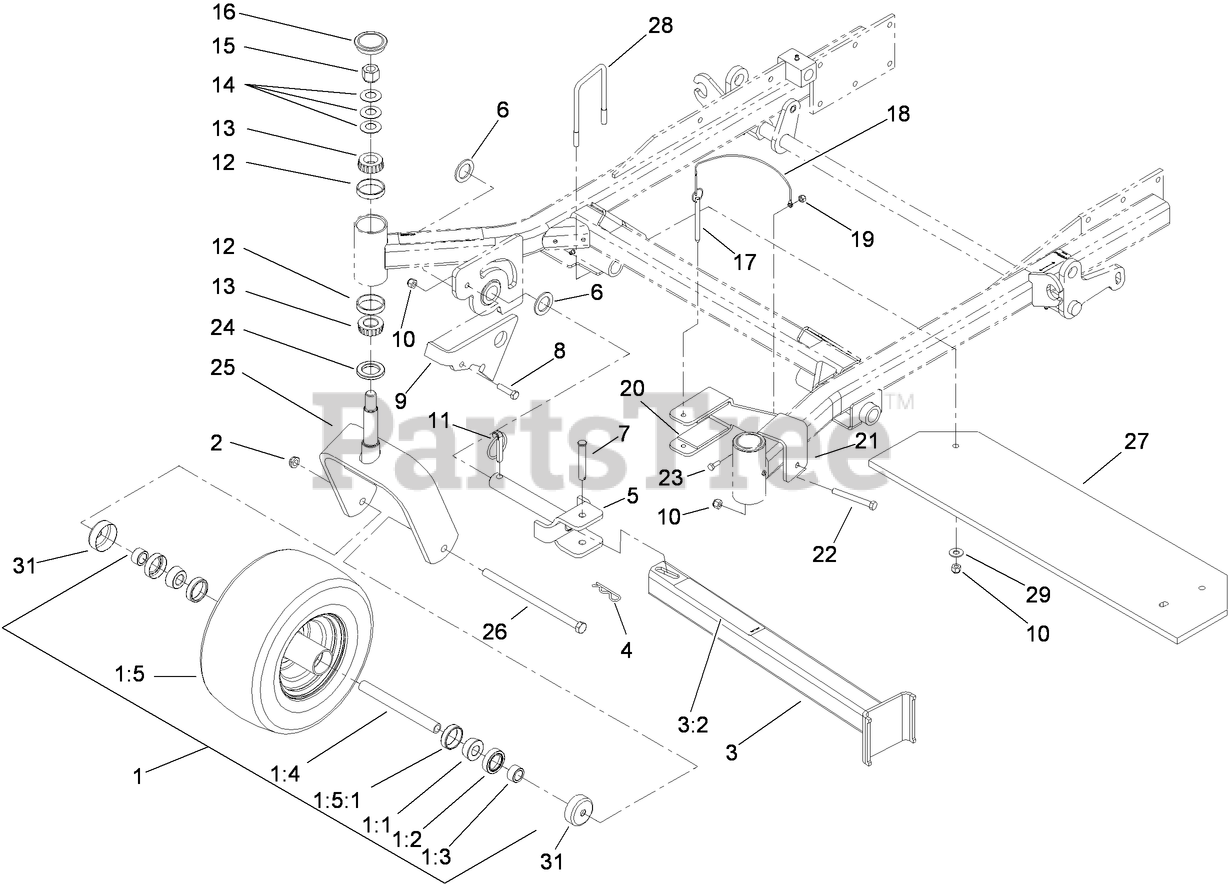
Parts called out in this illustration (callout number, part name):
1	WHEEL AND TIRE ASM
1:1	BEARING-CONE, TAPER
1:2	SEAL-CASTER
1:3	SPACER-NUT
1:4	AXLE-CASTER
1:5	WHEEL AND TIRE ASM
1:5:1	BEARING-CUP
2	NUT-LOCK, NI
3	Leg ASM
3:2	DECAL-Z STAND
4	PIN-HAIR
5	PIN-PIVOT
6	WASHER-THRUST
7	PIN-CLEVIS
8	SCREW-HH
9	BRACKET-LATCH
10	NUT-LOCK, NI
11	PIN-LYNCH
12	BEARING-CUP, TAPERED
13	BEARING-CONE, TAPERED
14	WASHER-BELLVILLE
15	NUT-LOCK, NI
16	CAP-GREASE
17	PIN-HITCH, COTTERLESS
18	LANYARD-NYLON
19	NUT-LOCK, NI
20	Cushion-Rubber
21	BRACKET-CRADLE
22	SCREW-HH
23	SCREW-HH
24	SEAL-GREASE
25	CASTER-FORK
26	Screw-HH
27	BAR-WEIGHT
28	U-BOLT, 3IN
29	WASHER-FLAT
31	GUARD-SEAL
